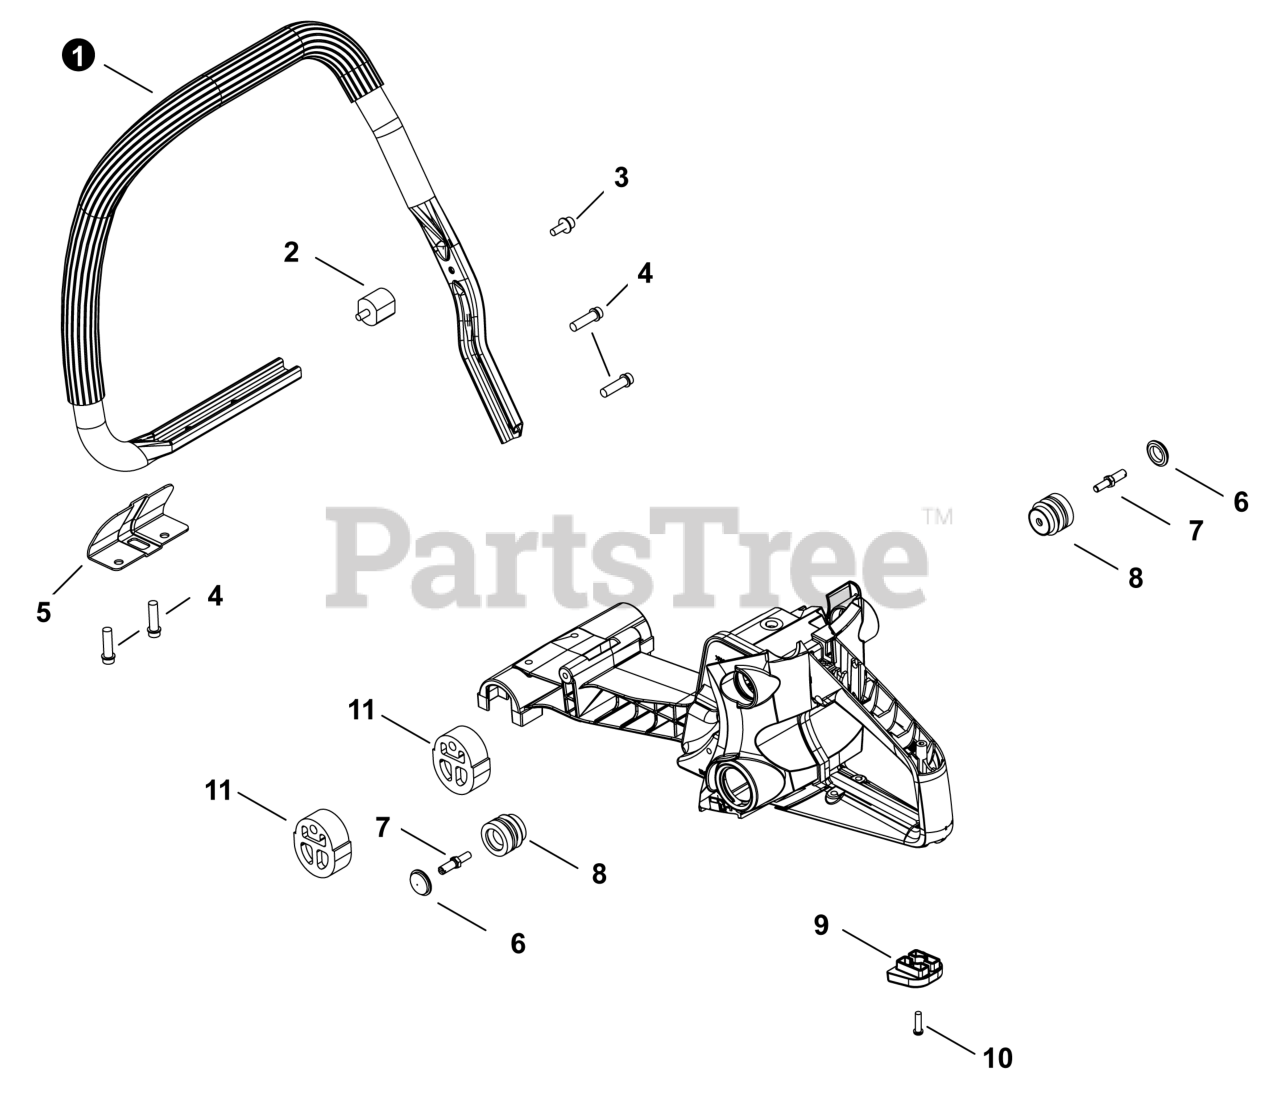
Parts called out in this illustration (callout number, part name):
1	HANDLE, FRONT
2	CUSHION 5
7	BOLT, STOPPER 26
8	CUSHION
9	CUSHION
10	SCREW 4
11	CUSHION
